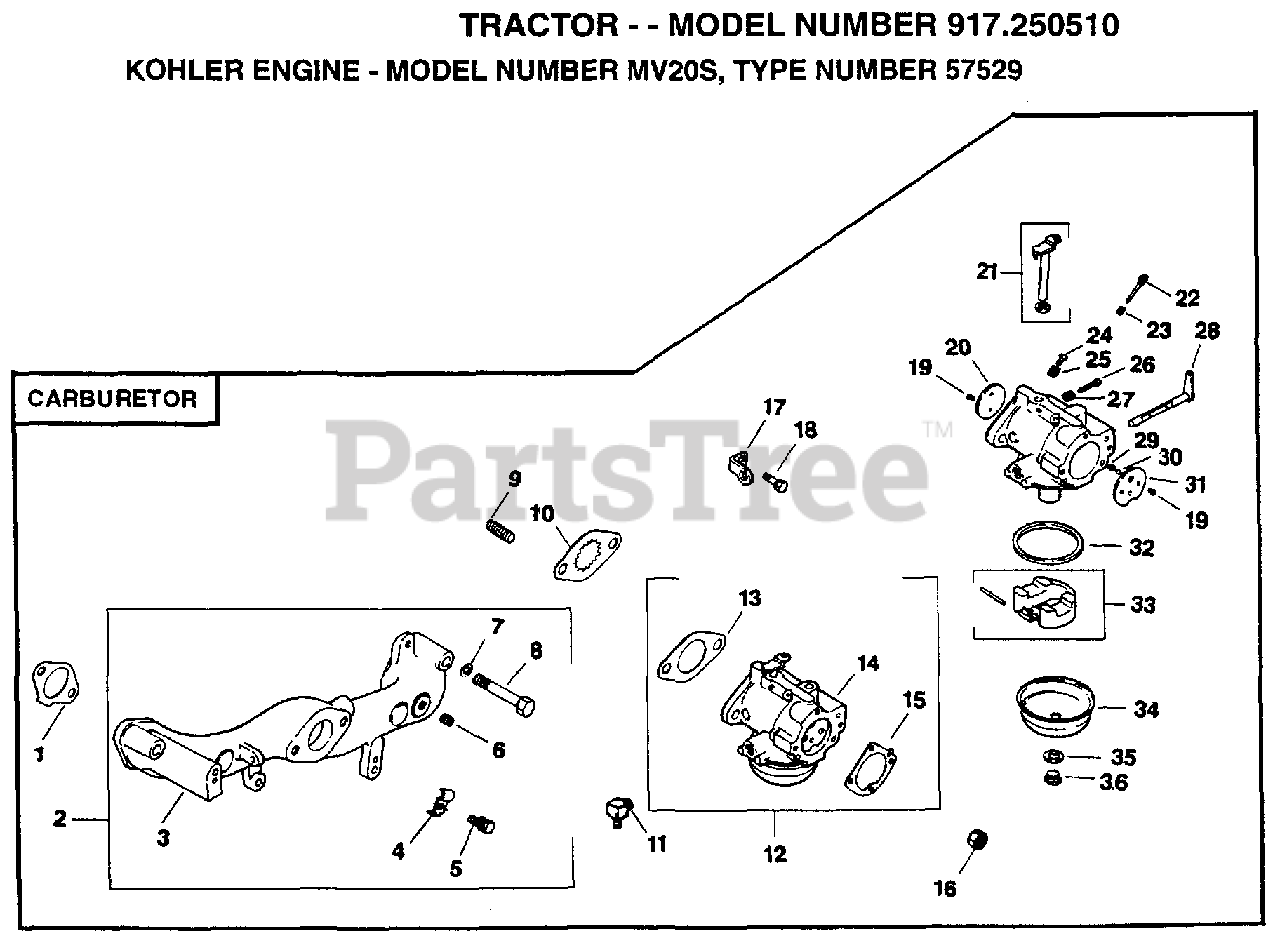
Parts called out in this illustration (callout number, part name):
4	CLAMP
5	SCREW
6	PLUG
7	WASHER
8	SCREW, 5/16-18X1-1/4 (4)
13	GASKET
15	GASKET, AIR CLEANER ELBOW
16	NUT
17	STRAP
18	SCREW
36	SCREW, BOWL RETAINER
